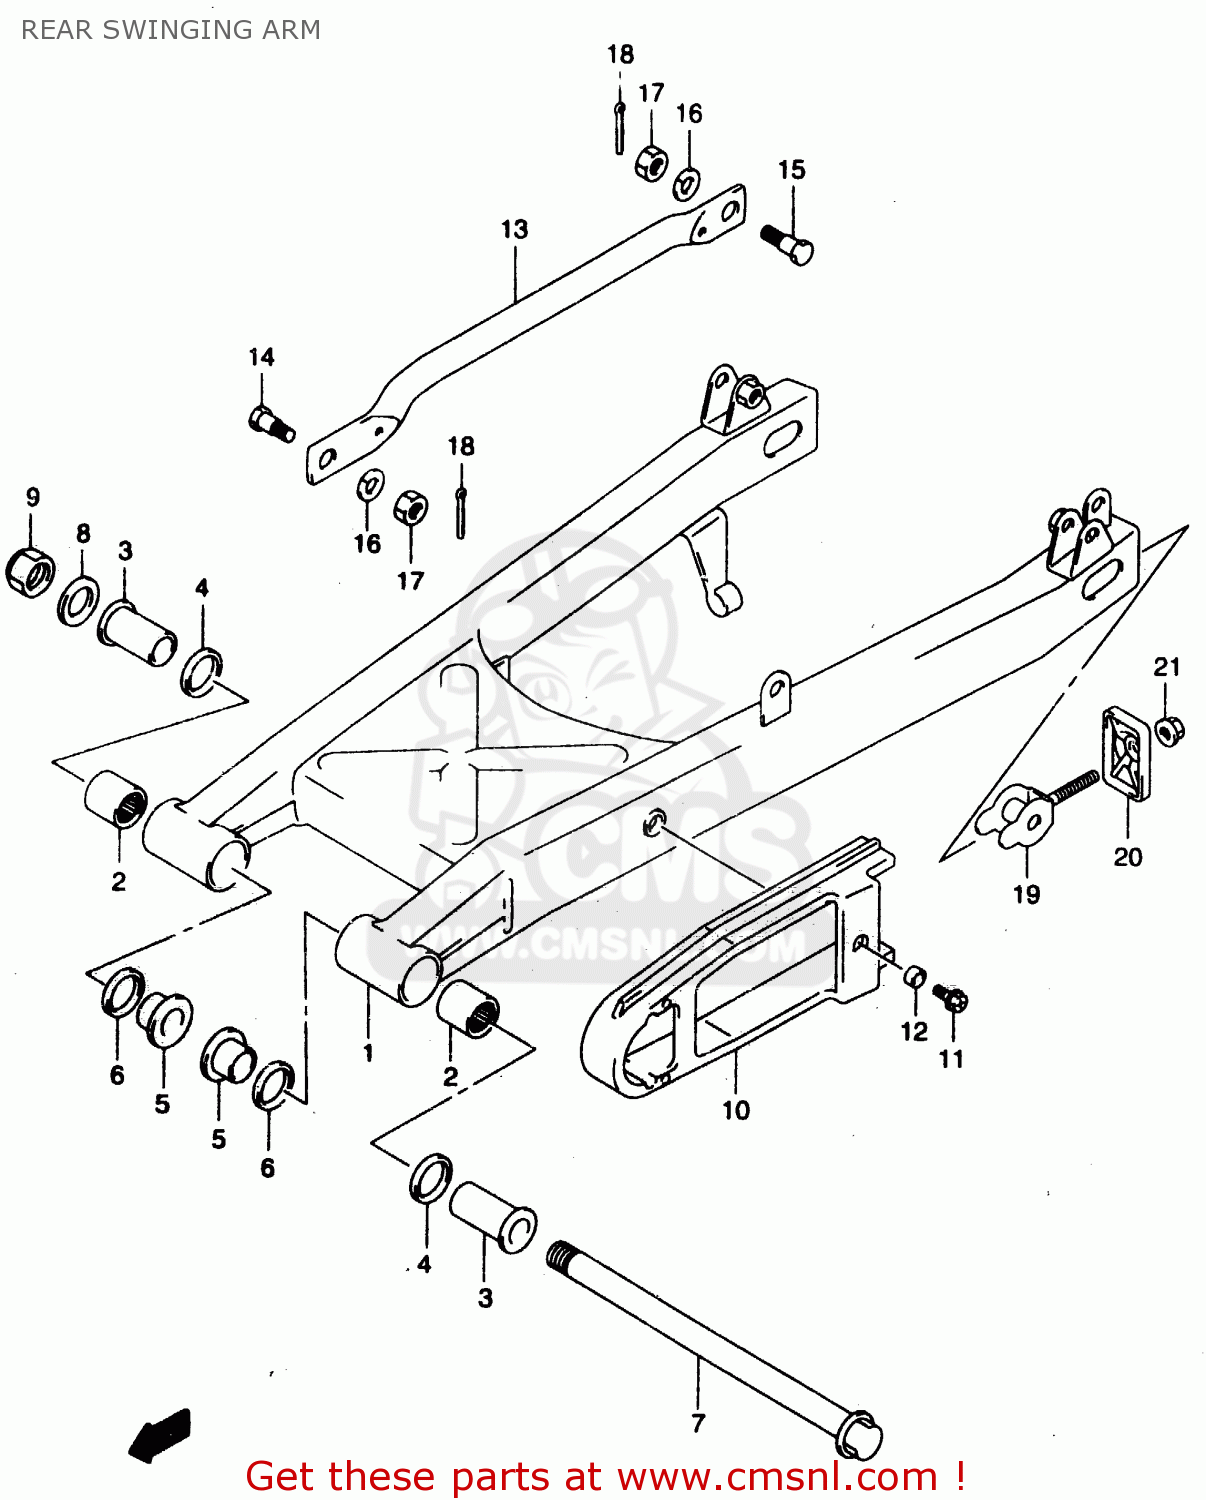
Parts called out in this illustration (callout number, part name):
1	SWINGINGARM ASSY,RR
2	BEARING(20X27X20)
3	SPACER,RR SWGARM PIVOT OUTER
4	SEAL,OIL(20X27X5)
5	SPACER,RR SWGARM PIVOT INNER
6	SEAL,OIL(20X27X5)
7	SHAFT,RR SWINGINGARM PIVOT
8	WASHER
9	NUT 14MM
10	BUFFER,CHAIN TOUCH DEFENSE
11	BOLT 6X20,WITH PLAIN WASHER
12	SPACER(6.5X9X3.8)
13	TORQUELINK,RR
14	BOLT(8X22.5)
15	BOLT(8X26.5)
16	WASHER,LOCK
17	NUT
18	PIN 20X20
19	ADJUSTER,CHAIN
20	PLATE,CHAIN ADJUSTER
21	NUT
